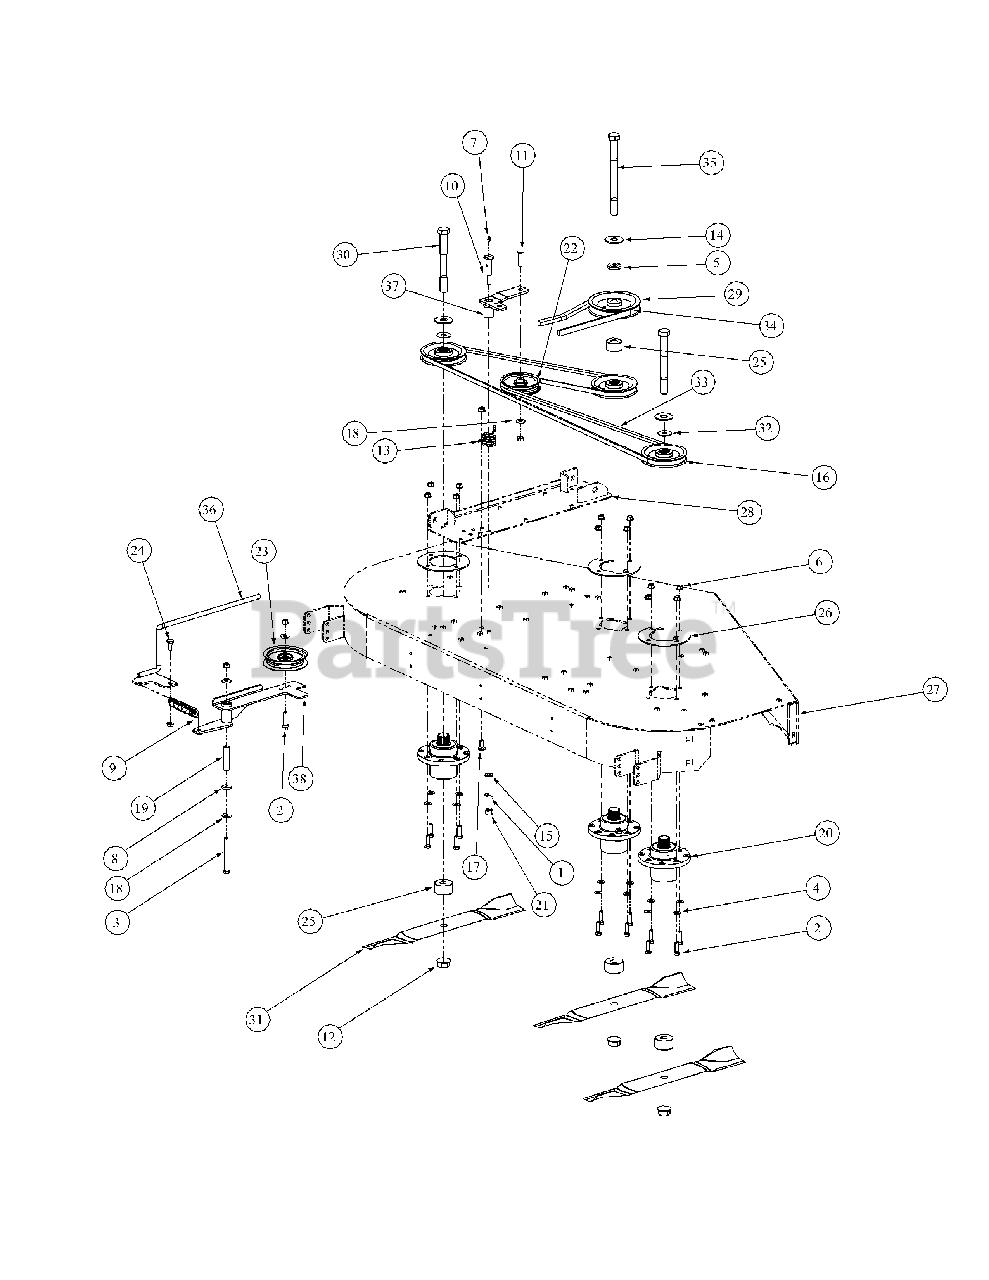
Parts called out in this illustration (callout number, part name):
1	Lock Washer, 7/16
2	Hex Cap Screw, 3/8-16 x 1-1/2
3	Hex Cap Screw, 3/8-16, 4.00
4	Flat Washer, 3/8
5	Caster Spacer
6	Flange Lock Hex Nut, 3/8-16
7	Grease Fitting, 1/4-28 x 3/16
8	Idler Washer
9	Extension Spring, 1.0 x OD x 5.125
10	Shoulder Screw, 7/16-14
11	Hex Carriage Screw, 3/8-16,1.75
12	Flange Hex Nut, 3/4-16
13	Torsion Idler Spring
14	Flat Washer, .781 ID 2.00 OD,.105
15	Flat Washer, .469 ID, .875 OD, .105
16	V-Pulley, 5.00 OD
17	Carriage Bolt, 3/8-16 x 1
18	Flat Washer, .406 ID, 1.0 OD, .105
19	Spacer, .39 ID x .625 OD x 2.75
20	Aluminum Spindle Assembly
21	Hex Nut, 7/16-14
22	Flat Pulley
23	Idler Pulley, 4.06 OD
24	Shoulder Screw, .50 x .27 Lg., 3/8-16
25	Spacer, .760 ID x 2.00 OD x 1.1
26	Aluminum Spindle Support Plate
27	60 Deck Assembly
28	Left Hand Mount Deck Bracket Assembly
29	V-Pulley, 5.774 OD
30	Hex Cap Screw, 3/4-16, 7.00
31	Hi-Lift Blade, 21.0, 0.756 ID
32	Spacer .812 ID x .268 LG
33	V-Belt, A Section x 122.3
34	V-Belt, B Section x 91.2
35	Hex Cap Screw, 3/4-16, 9.00
36	Spring Tension Rod Assembly
37	Idler Arm Assembly, Deck Spindle
38	Idler Arm Assembly, Flat Top Bearing
38	Bearing Sleeve
38	Decal, Idler Location
